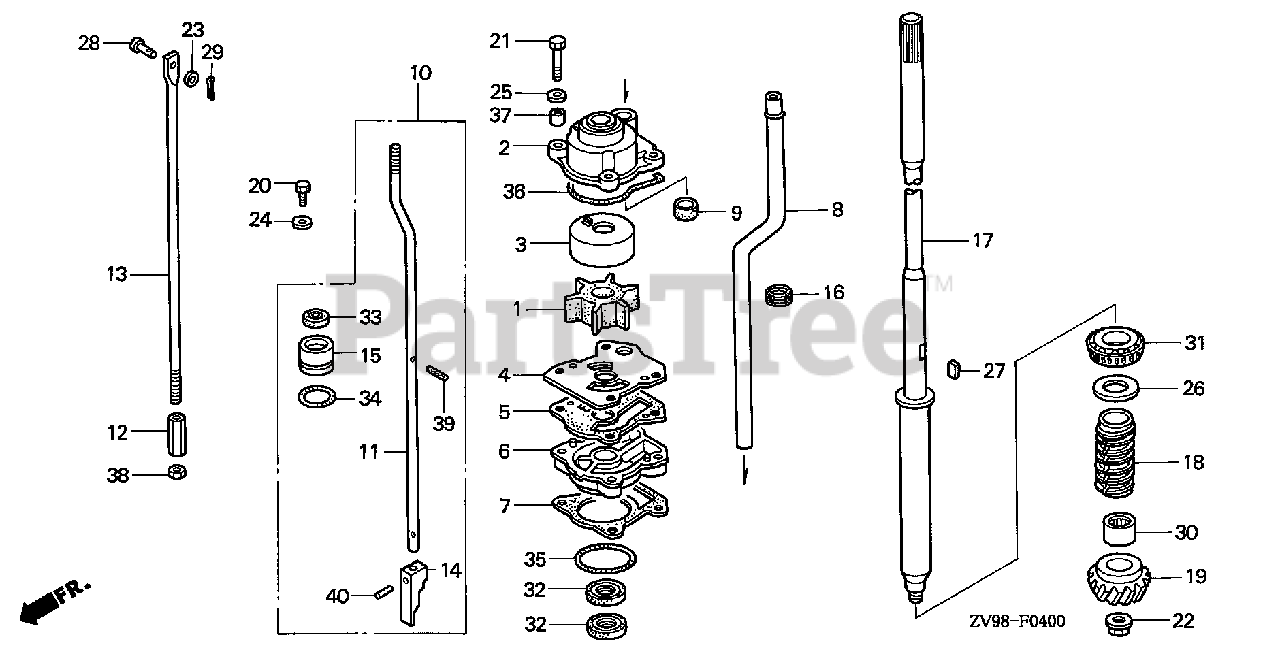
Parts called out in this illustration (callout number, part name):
1	IMPELLER, PUMP
2	HOUSING, IMPELLER
3	LINER, PUMP
4	COVER, IMPELLER
5	GASKET B, IMPELLER
6	HOUSING, WATER PUMP
7	GASKET, WATER PUMP
8	TUBE, WATER (S)
9	RING, WATER TUBE SEAL
10	ROD, SHIFT (S)
11	ROD B, SHIFT (S)
11	ROD B, SHIFT (S) (NOT AVAILABLE)
12	JOINT, SHIFT ROD
13	ROD A, SHIFT
14	ROD, PUSH (NOT AVAILABLE)
14	ROD, PUSH
15	HOLDER, SEAL
16	GROMMET, EXTENSION CASE
17	SHAFT, VERTICAL (S)
18	SLINGER, OIL
20	BOLT, HEX. (6X12)
21	BOLT, HEX. (6X40)
22	NUT, SPECIAL (10MM)
23	WASHER, PLAIN (5MM)
24	WASHER, PLAIN (6MM)
25	WASHER (6MM)
26	SHIM, GEAR (40X46X0.10) (A)
26	SHIM, GEAR (40X46X0.15) (B)
26	SHIM, GEAR (40X46X0.30) (C)
26	SHIM, GEAR (40X46X0.50) (D)
27	KEY, WOODRUFF (5MM)
28	PIN (5X17)
29	PIN, SPLIT (1.6MM)
30	BEARING, NEEDLE (7/8X11/8X1)
31	BEARING (25X47X15)
32	SEAL, WATER (17X30X7)
33	SEAL, WATER (6MM)
34	O-RING (20.8X2.4)
35	O-RING (41.7X3.5)
36	O-RING, WATER PUMP
37	COLLAR, IMPELLER HOUSING
38	NUT, HEX. (6MM)
39	PIN, SPRING (2X12)
40	ROLLER (2.5X13.8)
40	ROLLER (2.5X11.8)
